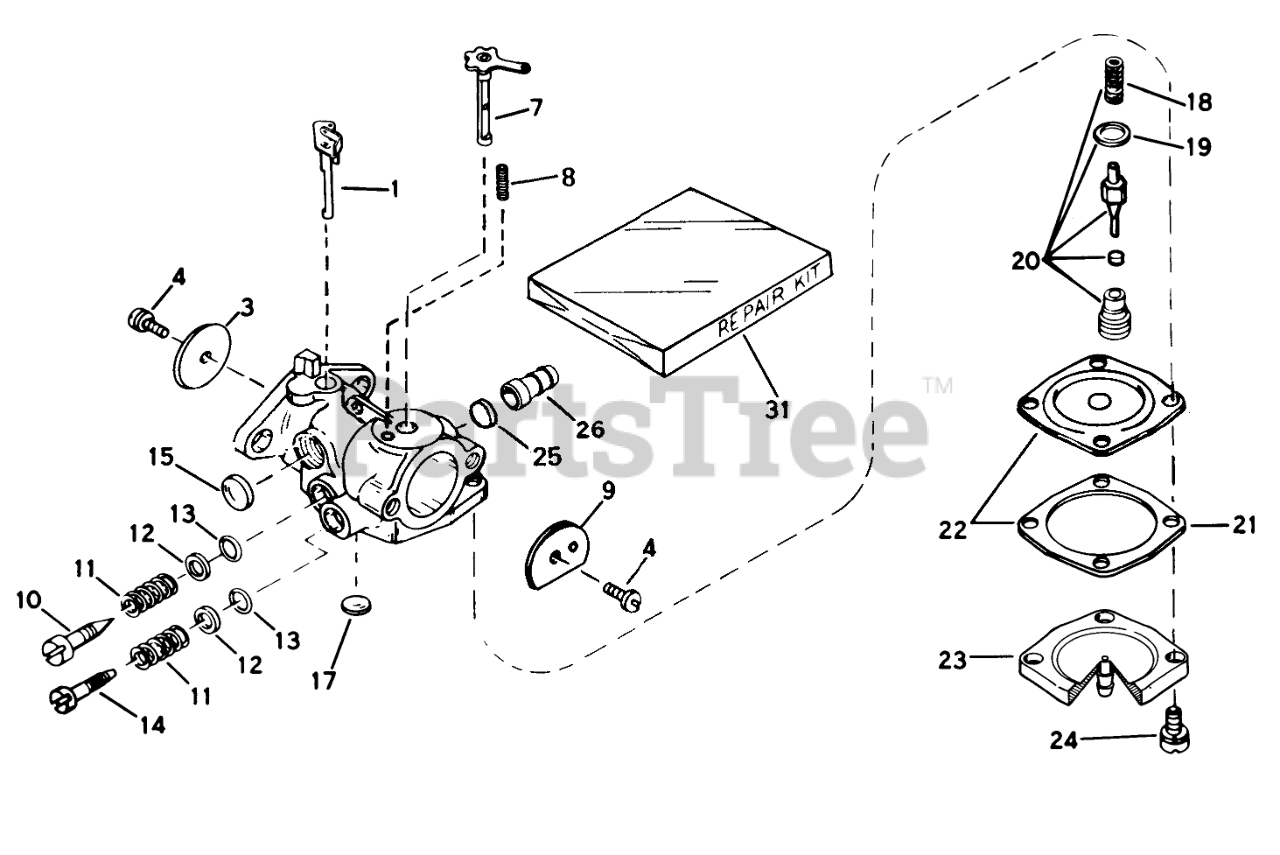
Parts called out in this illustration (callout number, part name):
1	Shaft/Lever-Throttle
3	Shutter-Throttle
4	Screw-Shutter
7	Shaft & Lever Assembly
8	Spring-Positioning, Choke
9	Shutter-Choke
10	Screw-Idle Adjustment
13	"O"Ring
14	Screw Main Adjustment
15	Plug-Welch, Idle Mixture Well
17	Plug, Welch
18	Spring-Valve
19	Gasket-Valve Seat
20	Inlet Needle, Seat, Spring & Gasket Assy. (Incl. Ref. #18 & 19)
21	Gasket-Diaphragm
22	Diaphragm Assy. (Incl. Ref. #21)
23	Cover, Diaphragm
25	Valve Check
26	Fuel Fitting
31	Kit-Repair
